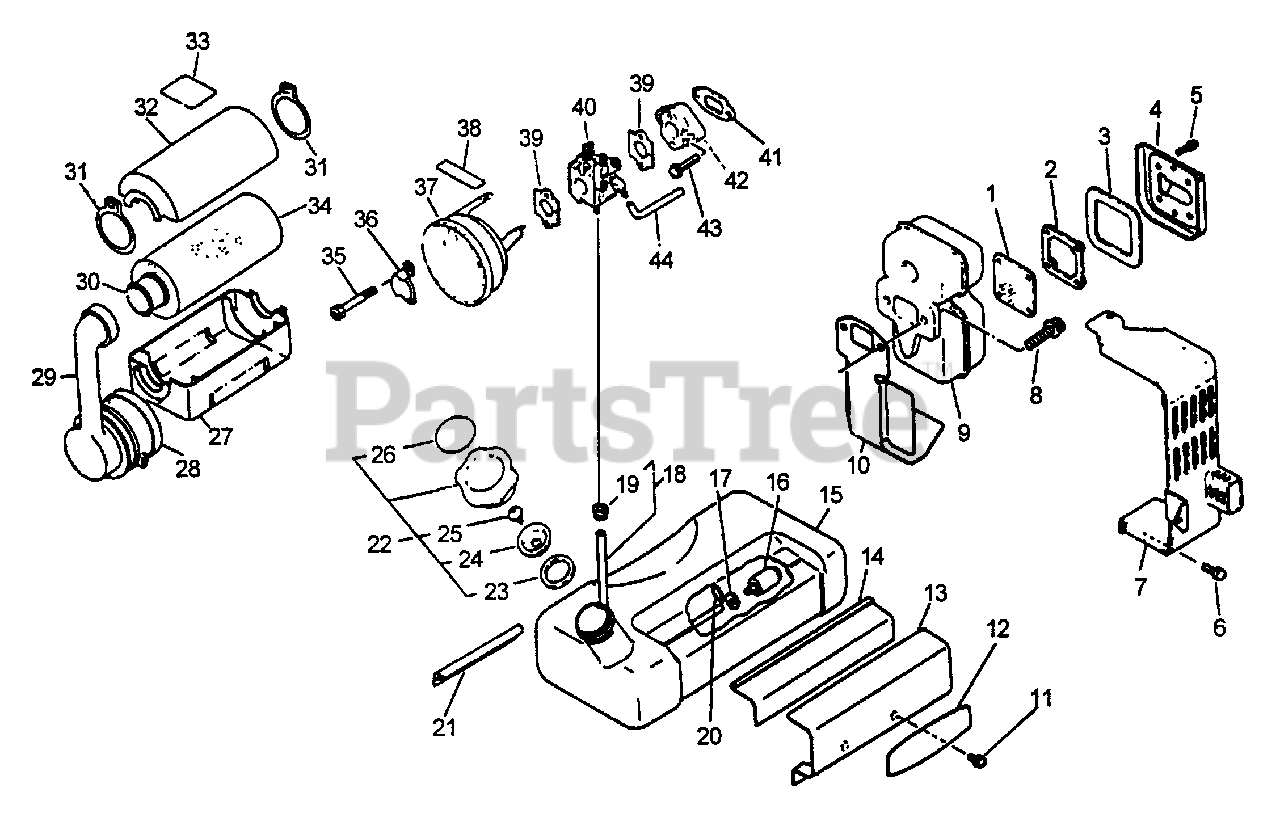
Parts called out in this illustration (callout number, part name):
1	SCREEN, SPARK ARRESTOR
2	RETAINER, SCREEN
3	GASKET, EXHAUST
4	GUIDE, EXHAUST
5	SCREW - 4X14
6	SCREW - 5X14
7	COVER, EXHAUST
8	SCREW - 6X20
10	GASKET, EXHAUST
11	SCREW - 5X10
12	LABEL - ECHO
13	BRACKET, FUEL TANK
14	CUSHION, FUEL TANK
15	TANK, FUEL
16	FILTER, FUEL
17	WASHER - 5
18	PIPE, FUEL - SPIRAL
20	CLIP - 6
21	CUSHION, FUEL TANK
22	CAP ASSY
23	GASKET, CAP
24	HOLDER, VENT
26	LABEL - FUEL MIX
27	CASE, AIR FILTER
29	ADAPTOR, INTAKE
30	FILTER, AIR
30	AIR CLEANER ASSY
32	COVER, AIR FILTER
33	LABEL - CAUTION
34	FILTER, AIR
35	SCREW - 5X55
36	PLATE, PREVENT
37	CASE, AIR FILTER
38	LABEL - CHOKE
39	GASKET, INTAKE
40	CARBURETOR WT-410
41	GASKET, INTAKE
42	INSULATOR, INTAKE
43	SCREW - 6X25
44	PIPE - IMPULSE
